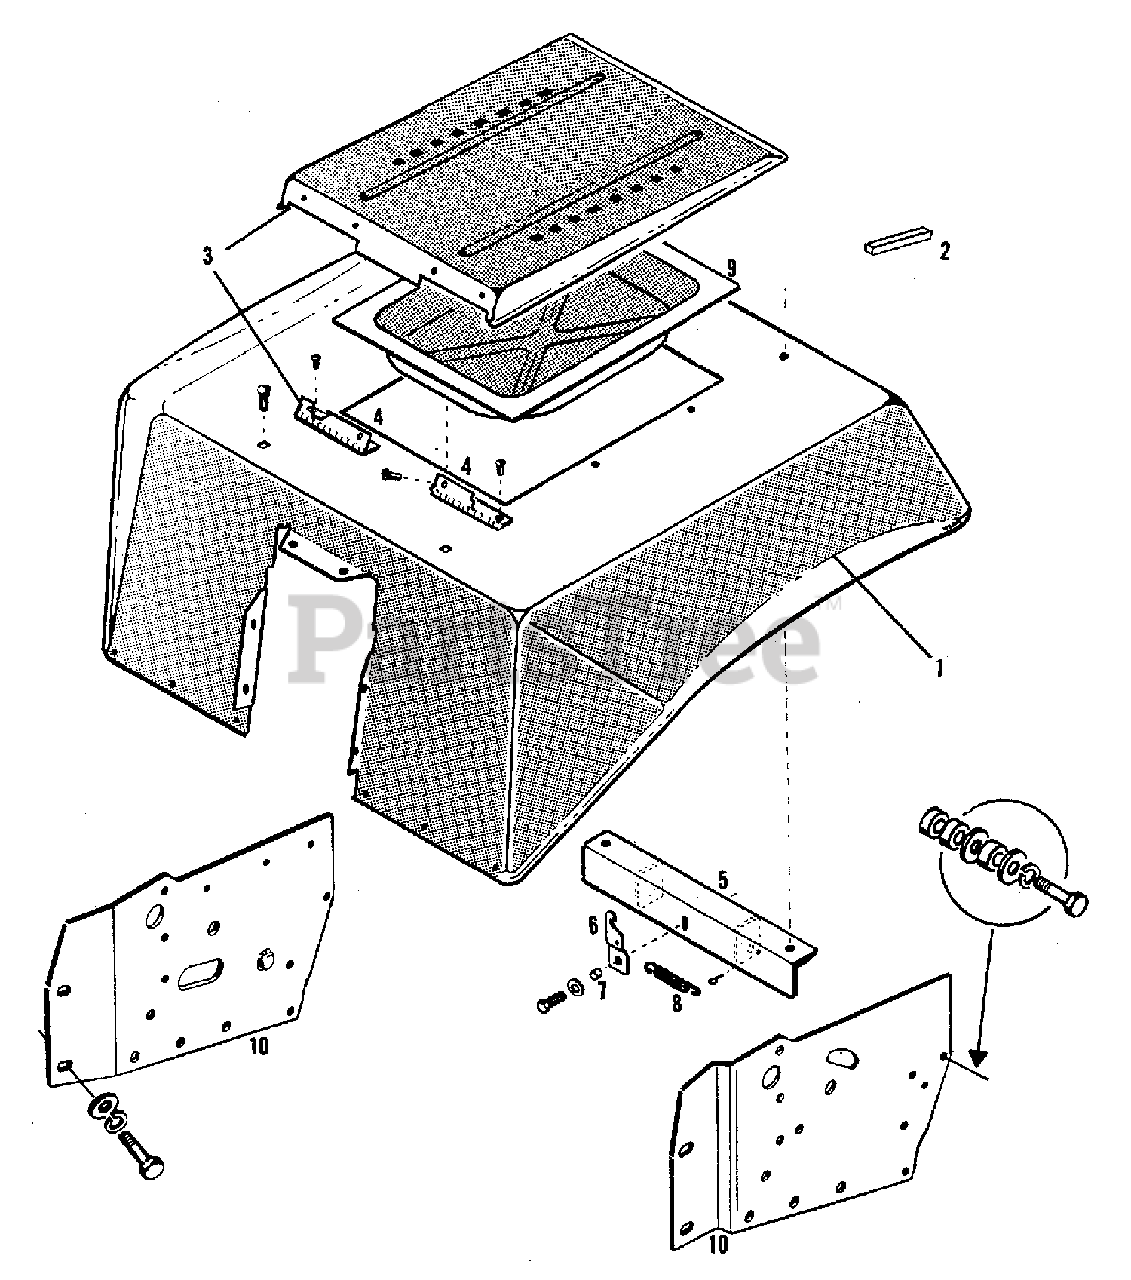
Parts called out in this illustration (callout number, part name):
1	DECK, Seat
1	CAPSCREW, 5/16NC x 5/8
1	LOCKWASHER, 5/16
1	NUT, 5/16NC
1	SCREW, 5/16NC x 1/2 Taptite
1	CAPSCREW, 1/4NC x 1/2
1	LOCKWASHER, 1/4
2	TAPE, Foam (Use 3 Strips-12" Long)
3	SUPPORT, Seat
4	RIVET, 3/16 x .402 Pop
5	SUPPORT ASSEMBLY, Seat Deck
5	CAPSCREW, 5/16NC x 1
5	LOCKWASHER, 5/16
5	NUT, 5/16NC
5	WASHER, 5/16 Standard
6	LATCH, Seat
6	WASHER .381 x 1 x 16 Ga
7	CAPSCREW, 5/16NC x 1
7	LOCKWASHER, 5/16
7	NUT, 5/16NC
7	WASHER, 13/32 x 7/8 x 14 GA
8	PIN, 3/16 x 1 Cotter
9	TRAY, Tool
10	PLATE, L.H. Side (Not for Hydrostatic Model)
10	PLATE, L.H. Side (Hydrostatic Model Only)
10	PLATE, R.H. Side (410 Without Shuttle)
10	PLATE, R.H. Side (All Shuttle Clutch Models)
10	PLATE, R.H. Side (Hydrostatic Model Only)
10	CAPSCREW, 7/16NC x 1-Gr5
10	CAPSCREW, 7/16NC x 1-Gr8 (Used w/1607709 Only)
10	NUT, 7/16NC
10	LOCKWASHER, 7/16
10	CAPSCREW, 7/16NC x 1-1/4 (w/ Hydrostatic Only)
10	WASHER, 7/16, Plain
11	REFLECTOR, Rear
11	CAPSCREW, 1/4NC x 3/4
11	NUT, 1/4NC
11	WASHER, 9/32 x 5/8 x 1/16
